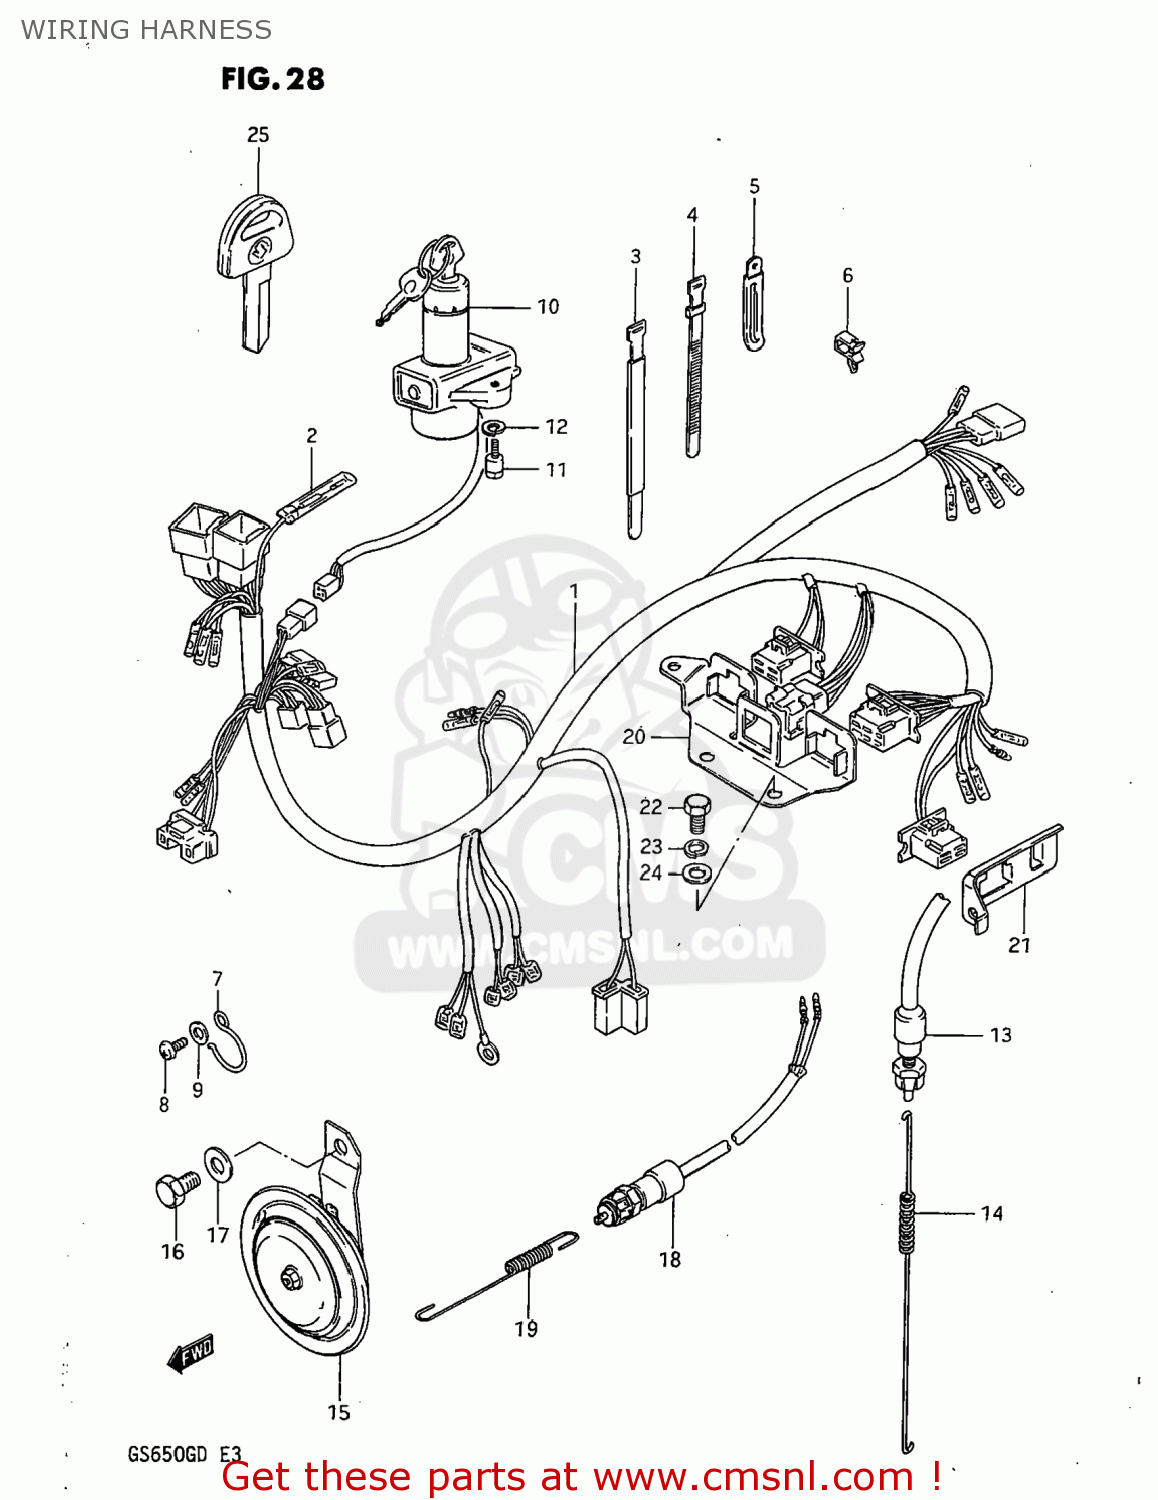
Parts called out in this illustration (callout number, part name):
1	HARNESS,WIRING
2	DIODE
3	CLAMP
4	CLAMP
5	CLAMP
6	CLIP
7	GUIDE,WIRING HARNESS
8	SCREW 6X12
9	WASHER
10	LOCK ASSEMBLY,STEERING
11	BOLT
12	LOCK WASHER
13	SWITCH ASSEMBLY,STOP LAMP
14	SPRING
15	HORN ASSEMBLY
16	BOLT 8X12
17	WASHER
18	SWITCH ASSEMBLY,SIDE STAND
19	SPRING
20	PLATE, COUPLER HOLDER (A)
21	PLATE, COUPLER HOLDER (B)
22	BOLT
23	LOCK WASHER
24	WASHER
25	KEY,BLANK
